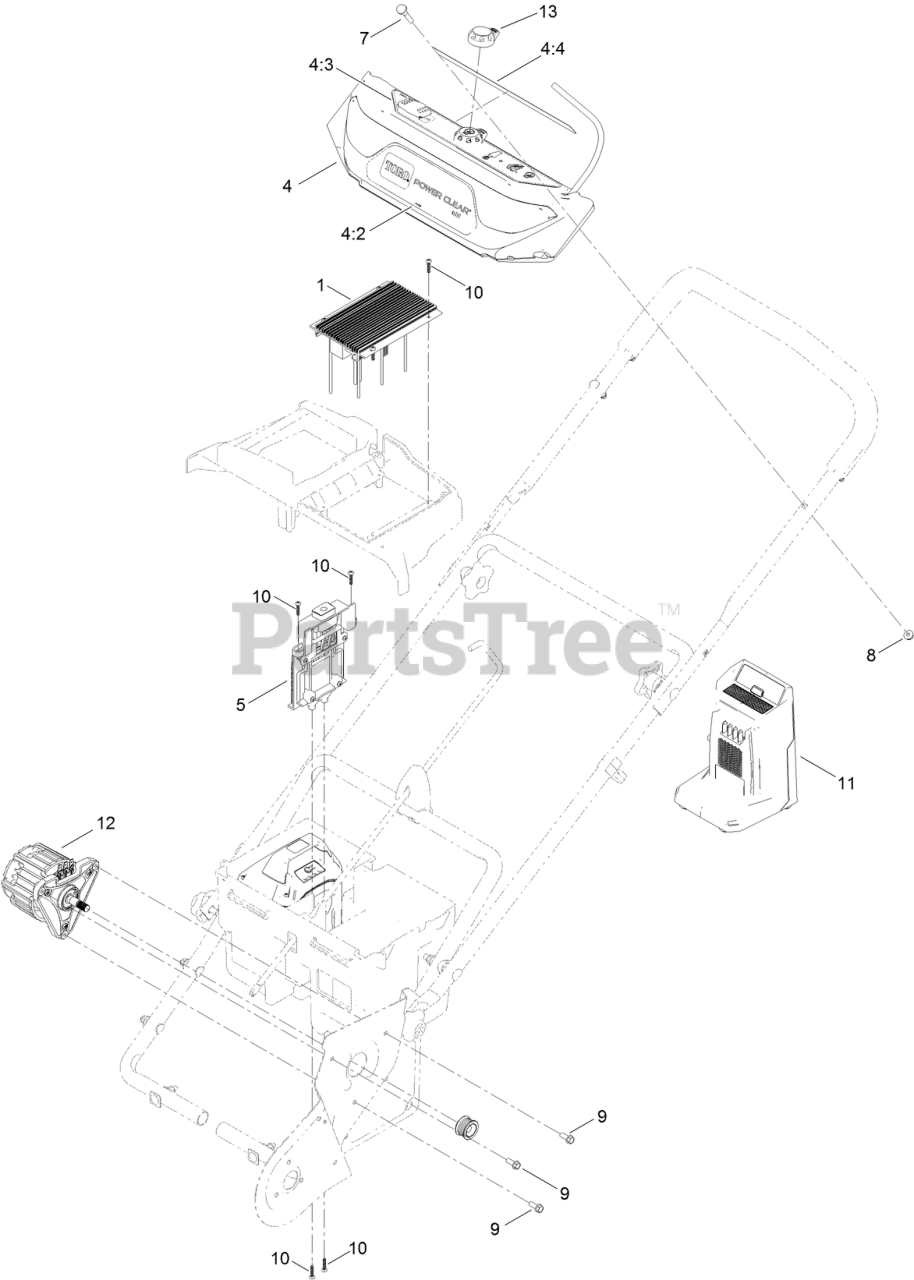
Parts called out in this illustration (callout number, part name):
1	MOTOR-DRIVER, SNOW (60V)
4	DASH PANEL ASM W/DECALS
4:2	DECAL-POWER CLEAR
4:3	DECAL-OPERATION
4:4	DECAL-CAUTION
5	BATTERY TRACK ASM
7	SCREW-HANDLE
8	NUT-HF
9	SCREW-HWH
10	SCREW-PPH
11	CHARGER-60V (2A)
12	MOTOR ASM
13	KEY-BAIL
